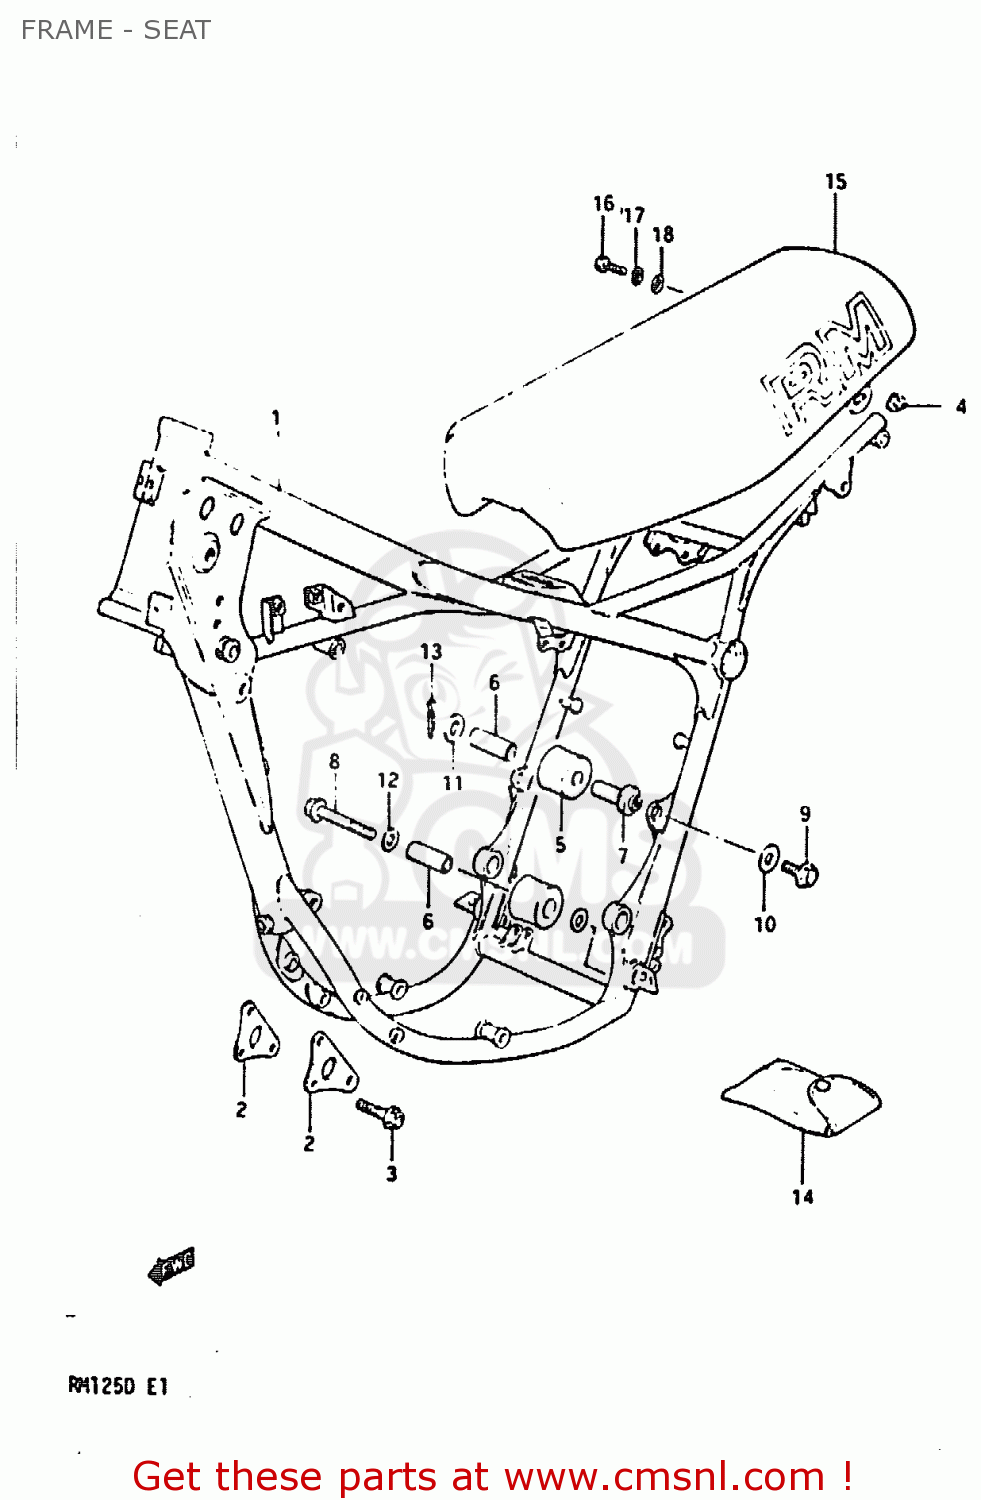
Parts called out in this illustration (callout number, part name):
1	FRAME
2	PLATE,ENG MTG
3	BOLT(8X36)
4	PLUG(OD:17)
5	ROLLER,CHAIN LENGTH CONTROL
6	SPACER,CHAIN LENGTH ROLLER
7	BOSS,CHAIN LENGTH ROLL
8	BOLT(8X45)
9	BOLT
10	WASHER
11	WASHER
12	WASHER
13	PIN 25X20
14	TOOL SET
15	SEAT ASSEMBLY
16	BOLT
17	LOCK WASHER
18	WASHER
